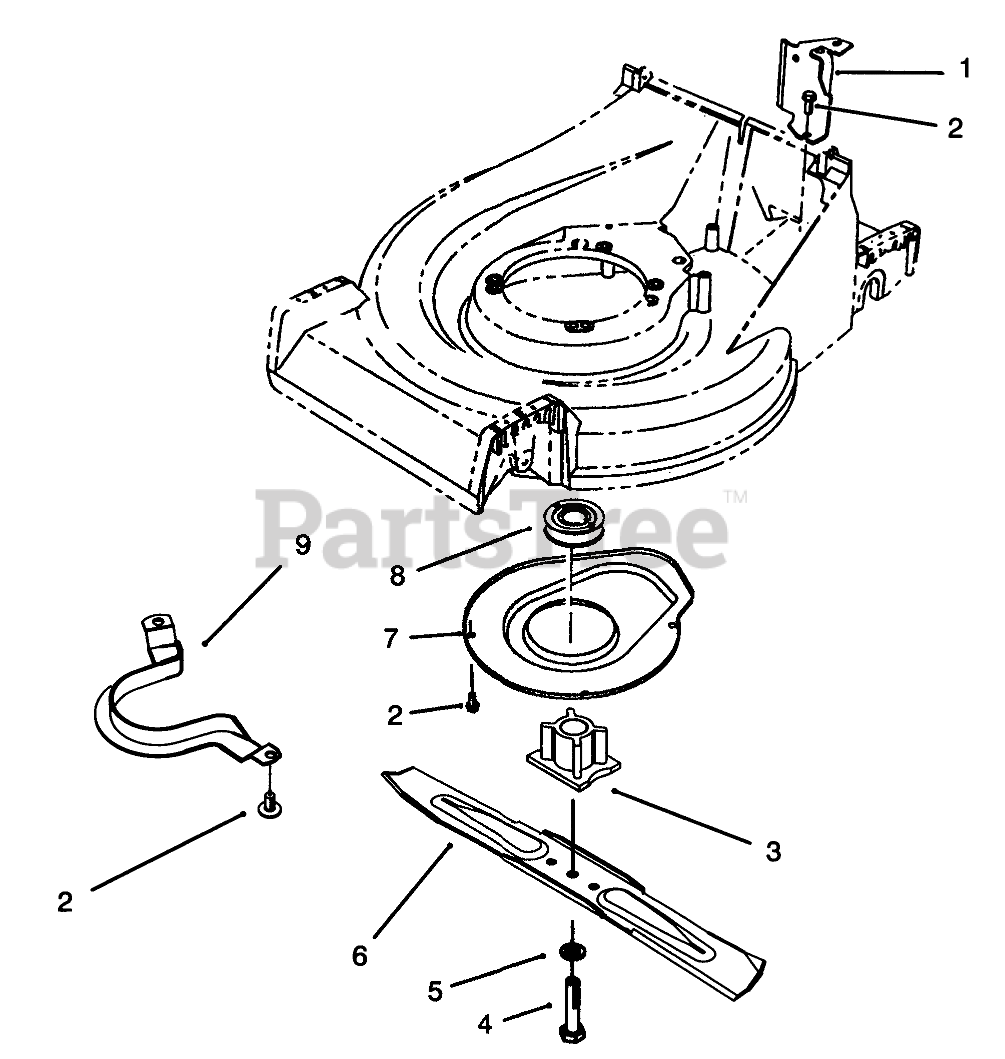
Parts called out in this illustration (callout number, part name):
1	Bracket-Cable Support
2	SCREW-HWHTF
3	BLADE RETAINER
4	SCREW-BLADE
5	WASHER-LOCK
6	Key
7	Cover
8	PULLEY-DRIVE, ZONE START
9	Guide-Belt
